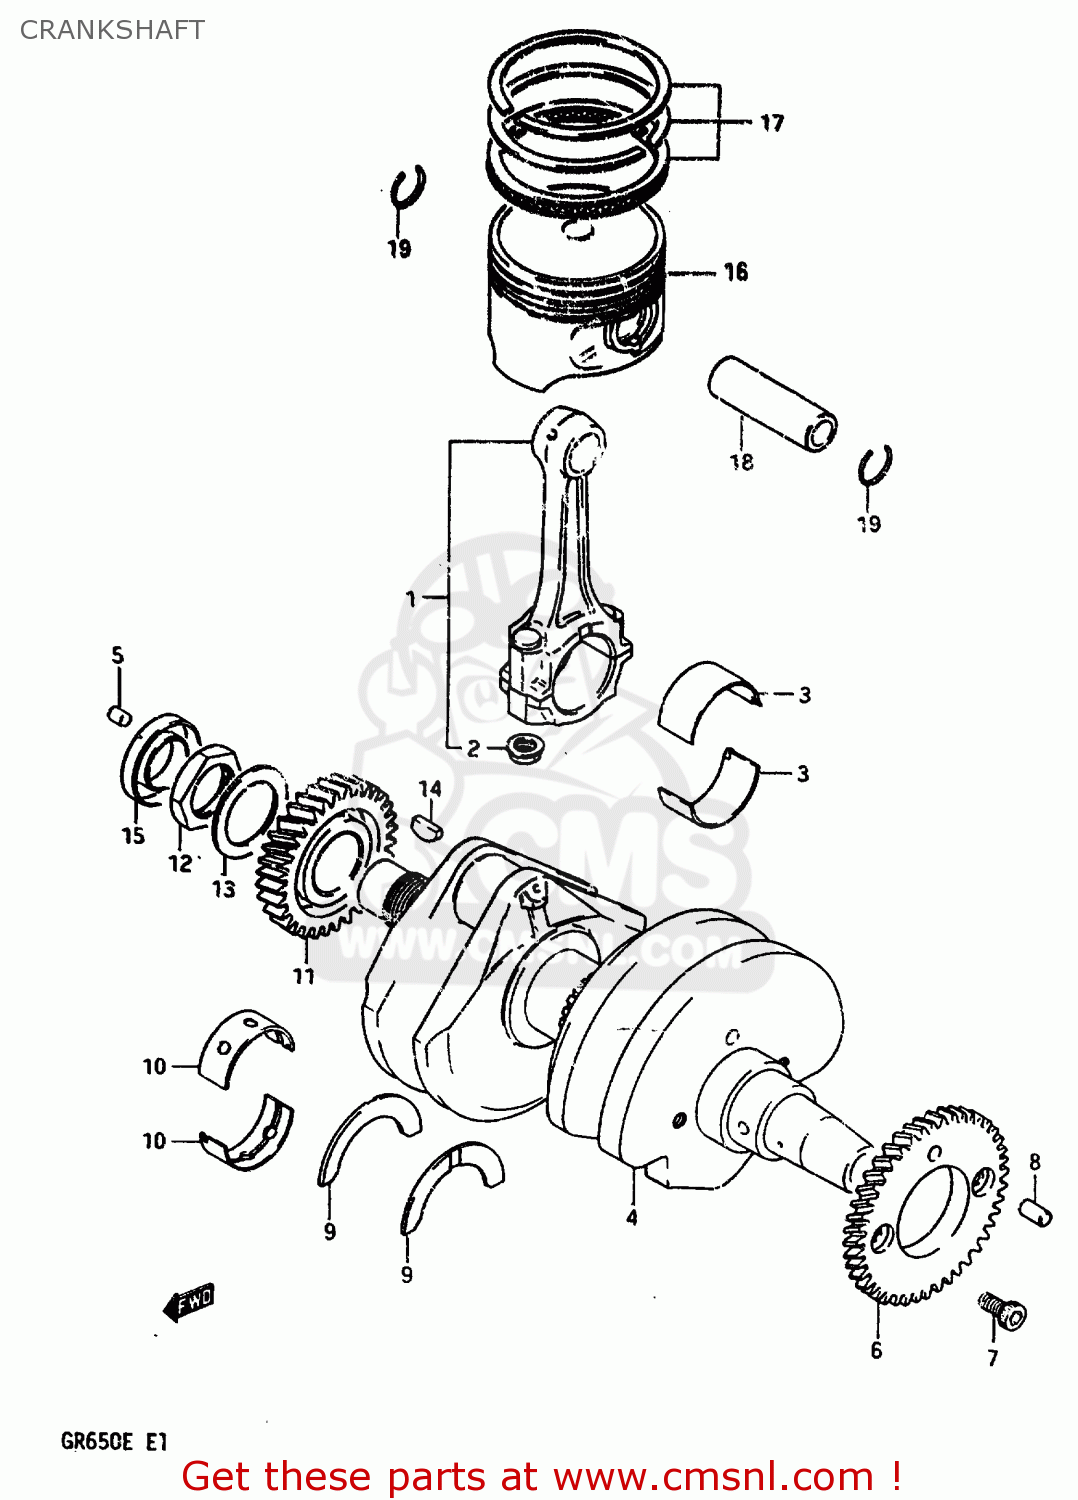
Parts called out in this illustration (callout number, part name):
1	CONNECTING ROD ASSEMBLY
2	NUT
3	METAL CRANK PIN (BROWN)
4	CRANKSHAFT
5	PIN
6	GEAR,CRANK BALANCER DRIVE
7	BOLT
8	PIN
9	PLATE,CRANK THRUST
10	METAL,CRANKSHAFT (GREEN)
11	GEAR,PRIMARY DRIVE
12	NUT
13	WASHER
14	KEY
15	SEAL,OIL(22X40X8)
16	PISTON (77.00MM)
17	RING SET,PISTON
18	PIN,PISTON
19	CIRCLIP,PISTON PIN
